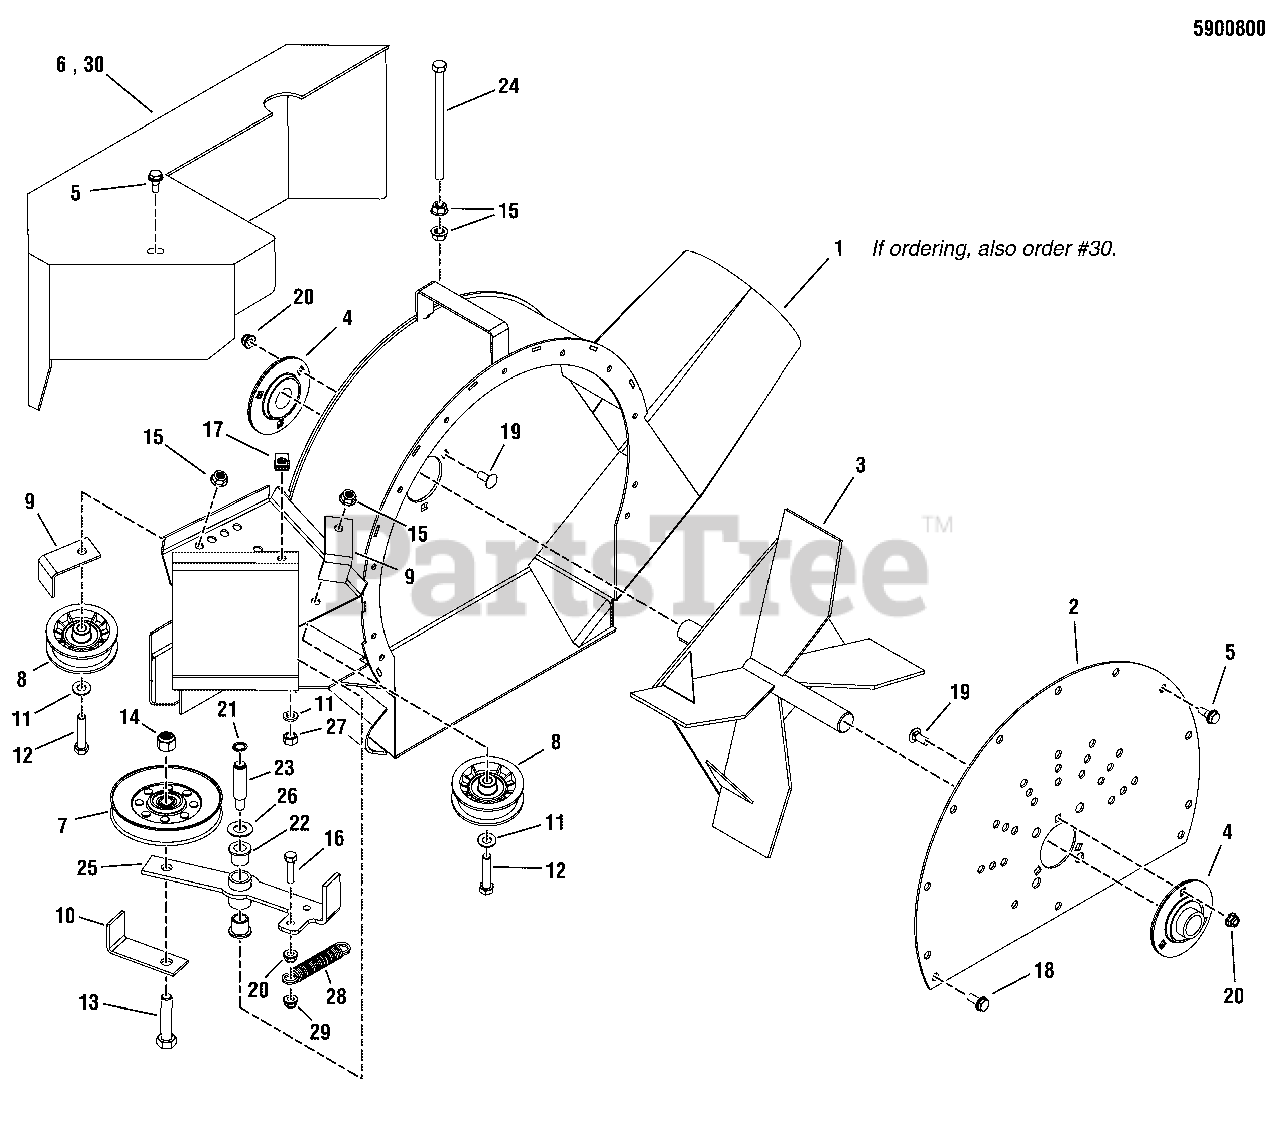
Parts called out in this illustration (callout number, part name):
1	**BLOWER HOUSING
2	BACK PLATE
4	BEARING, FLANGE, 1" Bore
5	BOLT, 5/16-18 X 3/4" Self Tapping
6	BELT GUARD
7	PULLEY, IDLER V-NOTCH, 5"
8	PULLEY, IDLER, 2.75 DIA X .376 ID
9	BELT KEEPER
10	KEEPER, BELT TENSIONER
11	WASHER, 3/8 SAE
12	BOLT, 3/8-16 X 2
13	BOLT, 1/2-13 X 2-1/2 GD5 YZ
14	NUT, 1/2-13 Hex Nylon Lock
15	NUT, 3/8-16 Hex Serrated Flange
16	BOLT, 5/16-18 X 1-1/4
17	U-CLIP, 5/16-18
18	BOLT, 5/16-18 X 1" Self-Tapping
19	CARRIAGE BOLT, 5/16-18 X 3/4
20	NUT, 5/16-18 Hex Nylock Flange
21	RETAINING RING, 1/2"
22	FLANGE BEARING, 9/16"
23	STUD, IDLER, Clear Zinc
24	BOLT, 3/8-16 X 6" GD5
25	WELD, IDLER ARM, FAST-VAC - BLK (Includes bushings)
26	WASHER, FLAT, 9/16 ID, 1-1/8 OD, 98THK
27	NUT, 3/8-24 HEX NYLON LOCK
28	SPRING, Extension
29	NUT, 5/16-18 Hex Center Lock
30	WELD, Fast-Vac Guard - BLK
31	GREASE FITTING, 65 DEG 1/4-28 TAPER MALE
